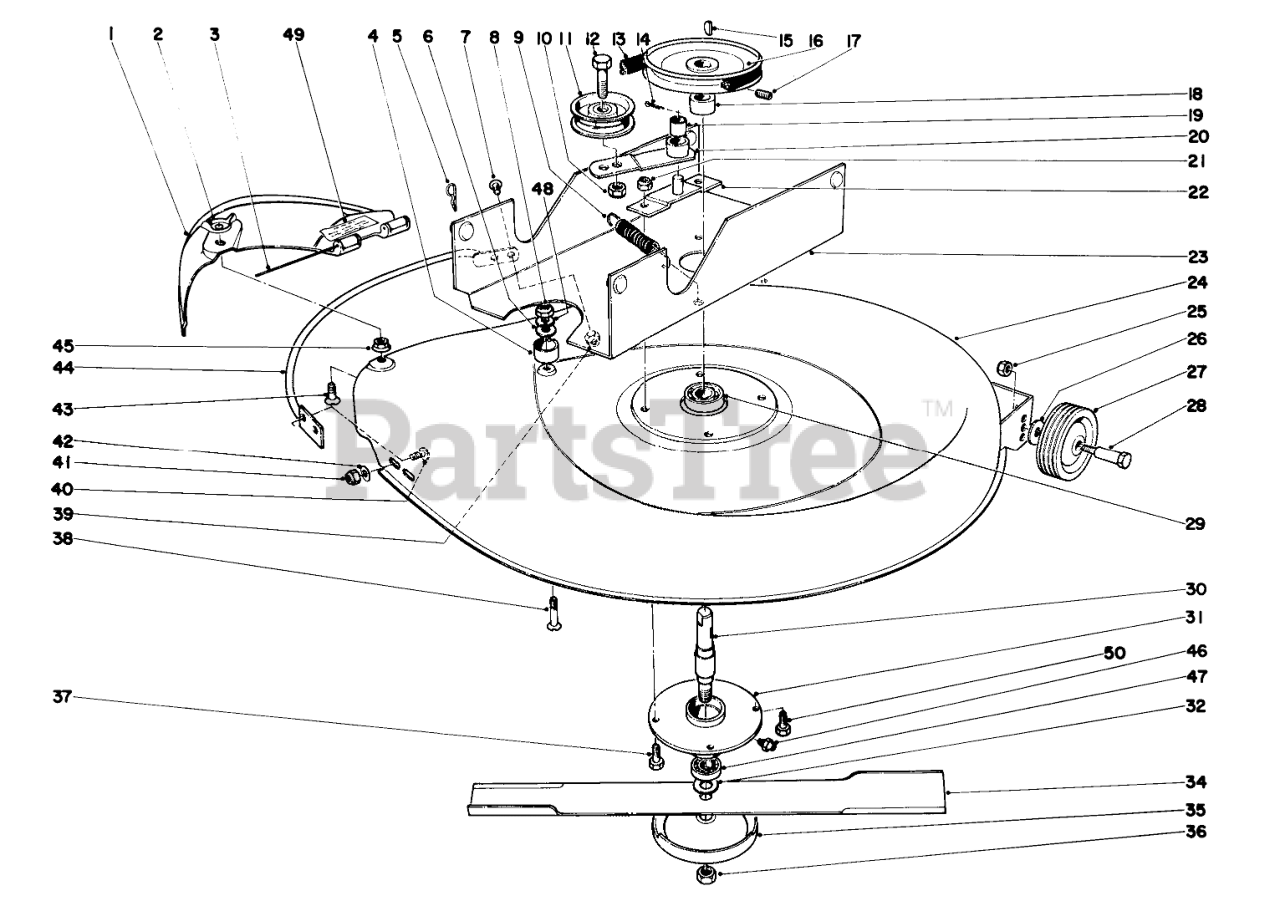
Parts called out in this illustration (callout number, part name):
1	DEFLECTOR
2	Wing Nut
3	Hinge Pin
4	Spacer
5	PIN-COTTER
6	WASHER-FLAT
7	5/16-18X5/8 TRS HD MS
8	NUT-HEX
9	Spring
11	Idler Pulley
12	SCREW-HH
13	FRONT PULLEY BELT
14	PIN-COTTER
15	KEY-WOODRUFF
16	PULLEY
17	SCREW-HSH
18	Spacer
19	Bushing
20	Idler Plate
21	Nut
22	Pivot Bracket
23	Channel
24	Housing
26	WASHER-FLAT
27	Wheel
29	Bearing
30	Blade Spindle
31	MOWER SPINDLE HOUSING
32	WASHER
34	Blade
35	Cup
37	SCREW-HH
38	Screw
39	Nut
42	WASHER-FLAT
43	5/16-18X7/8 FLT HD MS
44	Blade Guard
45	PAL NUT
46	FITTING-GREASE
47	.6693 RP BALL BEARING
48	WASHER-LOCK
49	Decal
50	SCREW-HH
